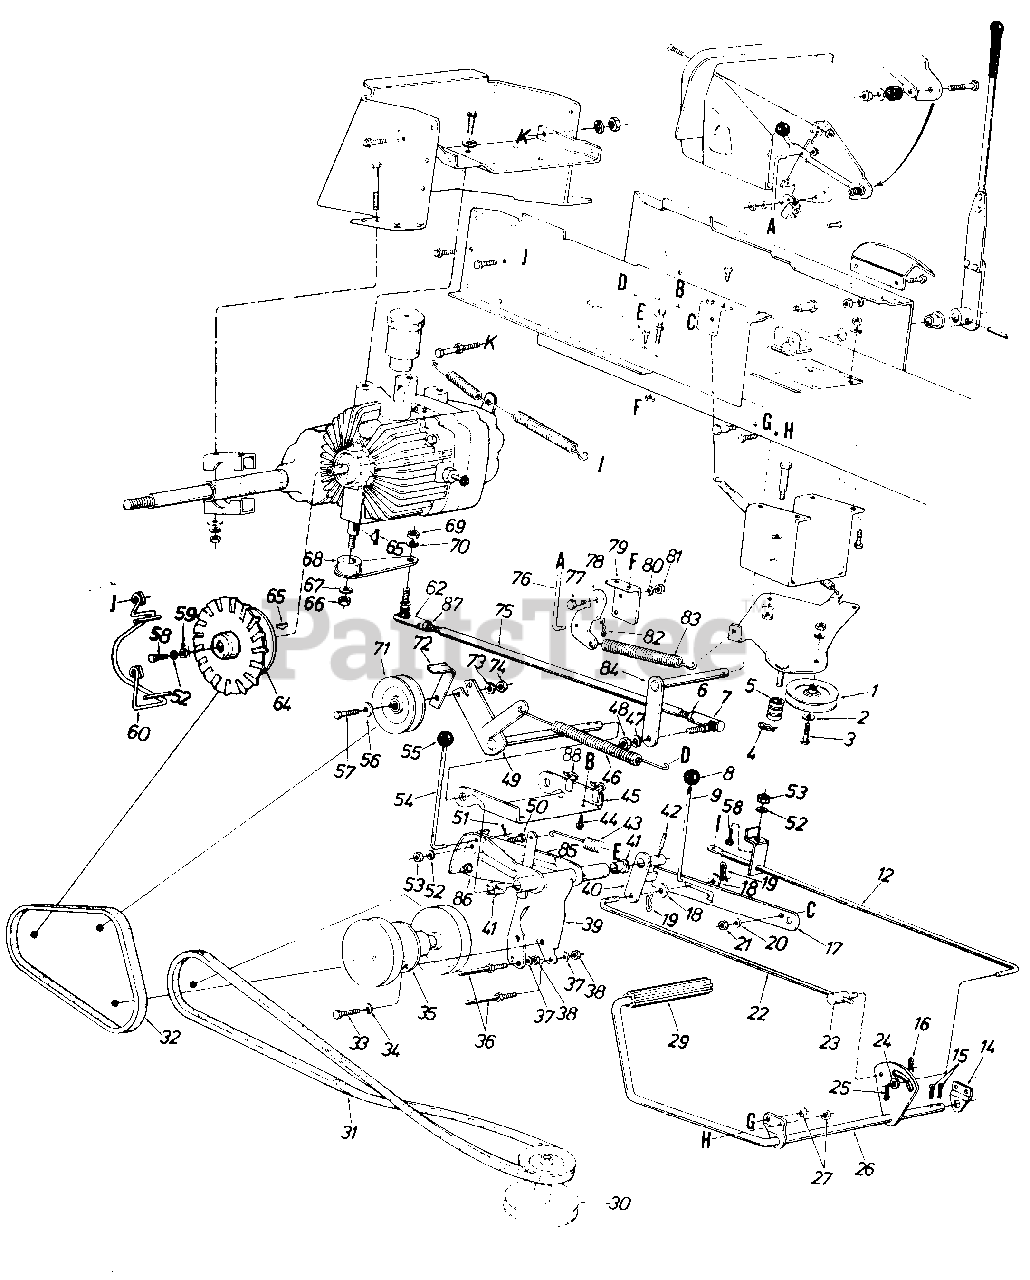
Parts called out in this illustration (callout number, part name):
1	4" Dia. "V"-Idler Pulley
2	Fl-Wash. 3/8" I.D.
3	Hex Bolt 3/8-16 x 1.25" Lg.
4	Intern. Cotter Pin 5/16" Dia.
5	Spacer
6	Hex Jam L-Nut 3/8-24 Thd.
7	Ball Joint Ass'y. 3/8-24 Thd.
8	Ball Knob
9	Parking Brake Link
12	Brake Rod
14	Clutch Rod Brg. Brkt.
15	Cotter Pin 1/8" Dia. x 1.00" Lg.
16	Hairpin Cotter 1/2" Dia.
17	Parking Brake Cam
18	Fl-Wash. .406 I.D. x 1.00" O.D. x .030
19	Hairpin Cotter 1/2" Dia.
20	L-Wash. 5/16" I.D.
21	Hex Nut 5/16-18 Thd.
22	Brake Cam Rod
23	Pivot Bushing
24	Fl-Wash. .401" I.D. x .749" O.D. x .057" Thk.
25	Cotter Pin 3/32" Dia. x .75" Lg.
26	Clutch Brake Pedal Ass'y.
27	Hex L-Nut 3/8-16 Thd.
29	Foot Pad
30	Two-Step Engine Pulley 4.75" and 5.56"
31	"V"-Belt 1/2 " x 59" Lg .
32	"V"-Belt 1/2 " x 37" Lg .
33	Hex Sems Bolt 5/16-18 x .75" Lg.
34	L-Wash. 5/16" I.D.
35	Jack Shaft Ass'y.
36	Stud 3/8-16 x 3.62" Lg.
37	L-Wash. 3/8" I.D.
38	Hex Nut 3/8-16 Thd.
39	Jack Shaft Mtg. Brkt. Ass'y.
40	Clutch Idler Horn Ass'y.
41	Nyliner 5/8" I.D. x .88" Lg.
42	Spring Pin Spiral 1/4" Dia. x 1.5" Lg.
43	Ext. Spring
44	Hex Wash. Hd. Self-Tap Scr. 1/4-20 x .50" Lg.
45	Idler Mtg. Brkt.
46	Ext. Spring
47	L-Wash. 3/8" I.D.
48	Hex Nut 3/8-24 Thd.*
49	Clutch Brkt. Ass'y.
50	Hex Bolt 1/4-20 x .50" Lg.
51	Internal Cotter Pin 5/16" Dia. Rod
52	L-Wash. 1/4" I.D.
53	Hex Nut 1/4-20 Thd.
54	Relief Valve Lockout Rod
55	Ball Knob
56	Fl-Wash. 3/8" I.D.
57	Hex Bolt 3/8-16 x 1.25" Lg.
58	Hex Bolt 1/4-20 x .62" Lg.
59	Fl-Washer
60	Belt Guard Ass'y.
64	Transaxle Pulley w/Fan
65	Hi-Pro Key 1/8" x 1/2" Dia.
66	Hex Nut 3/8-16 Thd.
67	L-Wash. 3/8" I.D.
68	Pintle Arm Ass'y.
69	Hex Nut 3/8-24 Thd.
70	L-Wash. 3/8" I.D.
71	41' "V"-Idler Pulley
74	Hex Nut 3/8-16 Thd.
75	Speed Control Rod
76	Deck Control Rod
77	Shld. Scr. .437" Dia. x .162" Lg. (5/16-18)
78	Deck Control Pivot Brkt.
79	Parking Brake Cam Mtg. Brkt.
80	L-Wash. 5/16" I.D.
81	Hex Nut 5/16-18 Thd.
82	Internal Cotter Pin 5116 Rod
83	Extension Spring
84	Speed Control Shaft Ass'y.
85	Relief Valve Cam-L.H.
86	Relief Valve Cam-R.H.
87	Hex Jam L-Nut 3/8-24 L.H. Thd.
88	Plastic Hose Clamp
